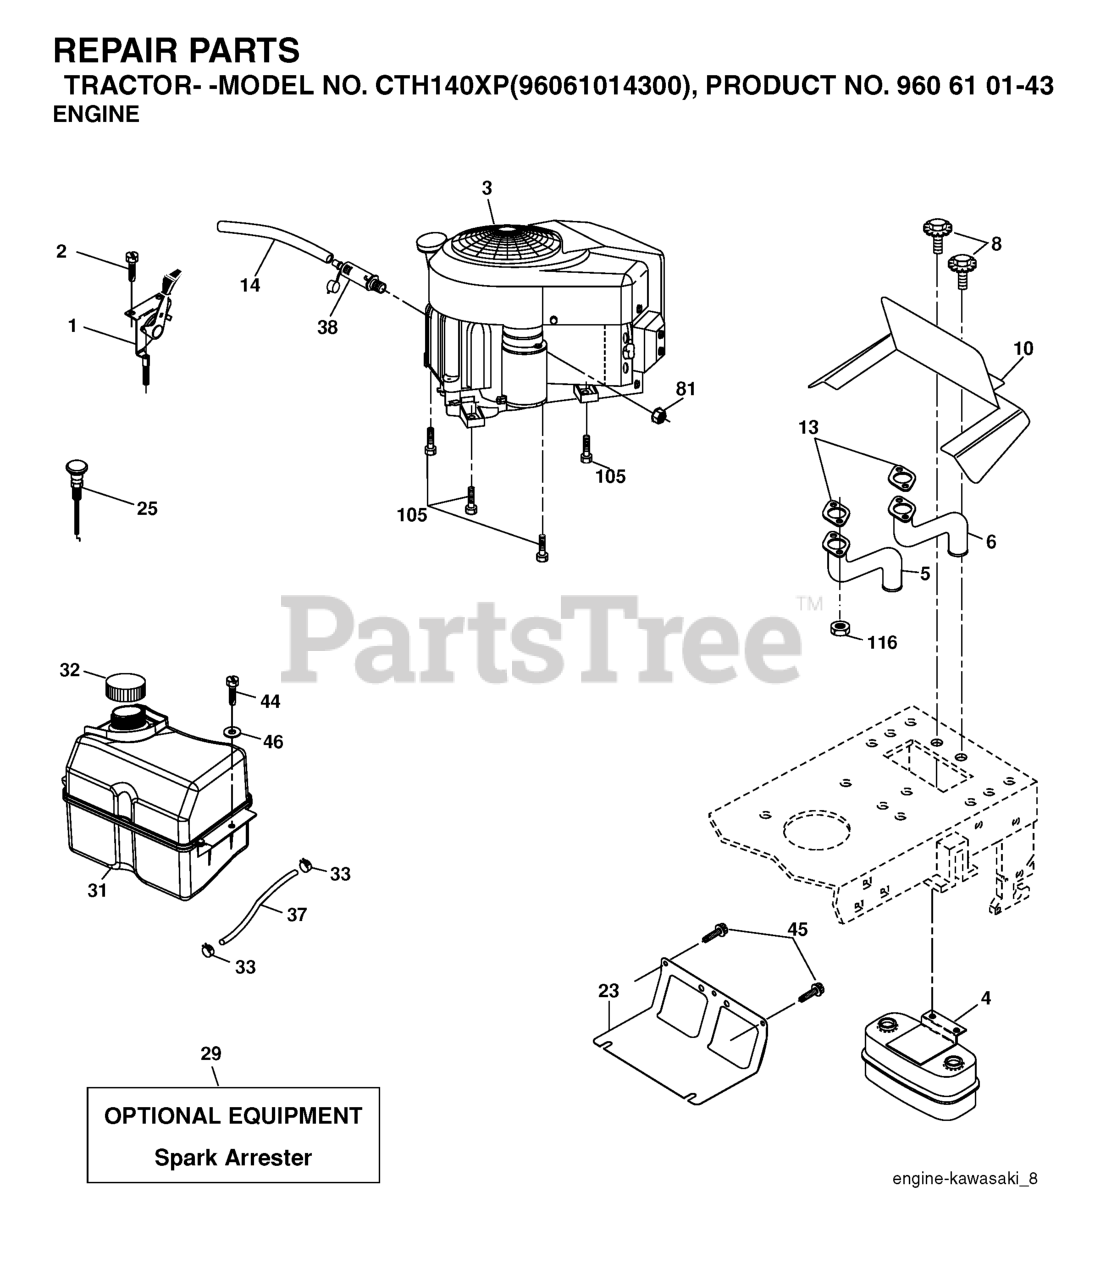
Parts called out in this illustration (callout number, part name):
1	CONTROL, THROTTLE
2	SCREW
4	MUFFLER.TWIN.CYL.LOW.TONE
5	EXHAUST TUBE LH KAWI
6	EXHAUST TUBE RH KAWI
8	BOLT.5/16-18UNCX3/4 W/SEMS.BLK
10	RP SHIELD HEAT MUFFLER
14	TUBE, DRAIN OIL ASM.
23	SHIELD.BROWNING.DBR.GUARD
29	KIT.SPARK ARRESTOR 794945 B&S
31	TANK FUEL
32	FUEL CAP
33	HOSE CLAMP
37	LINE.FUEL.20
44	SCREW HEXWSHR 1/4-20X3/4
45	SCREW, 3/8-16X3/4
81	NUT
105	SCREW 3/8-16X1
116	NUT.HEX.FLANGE.TOPLOCK
